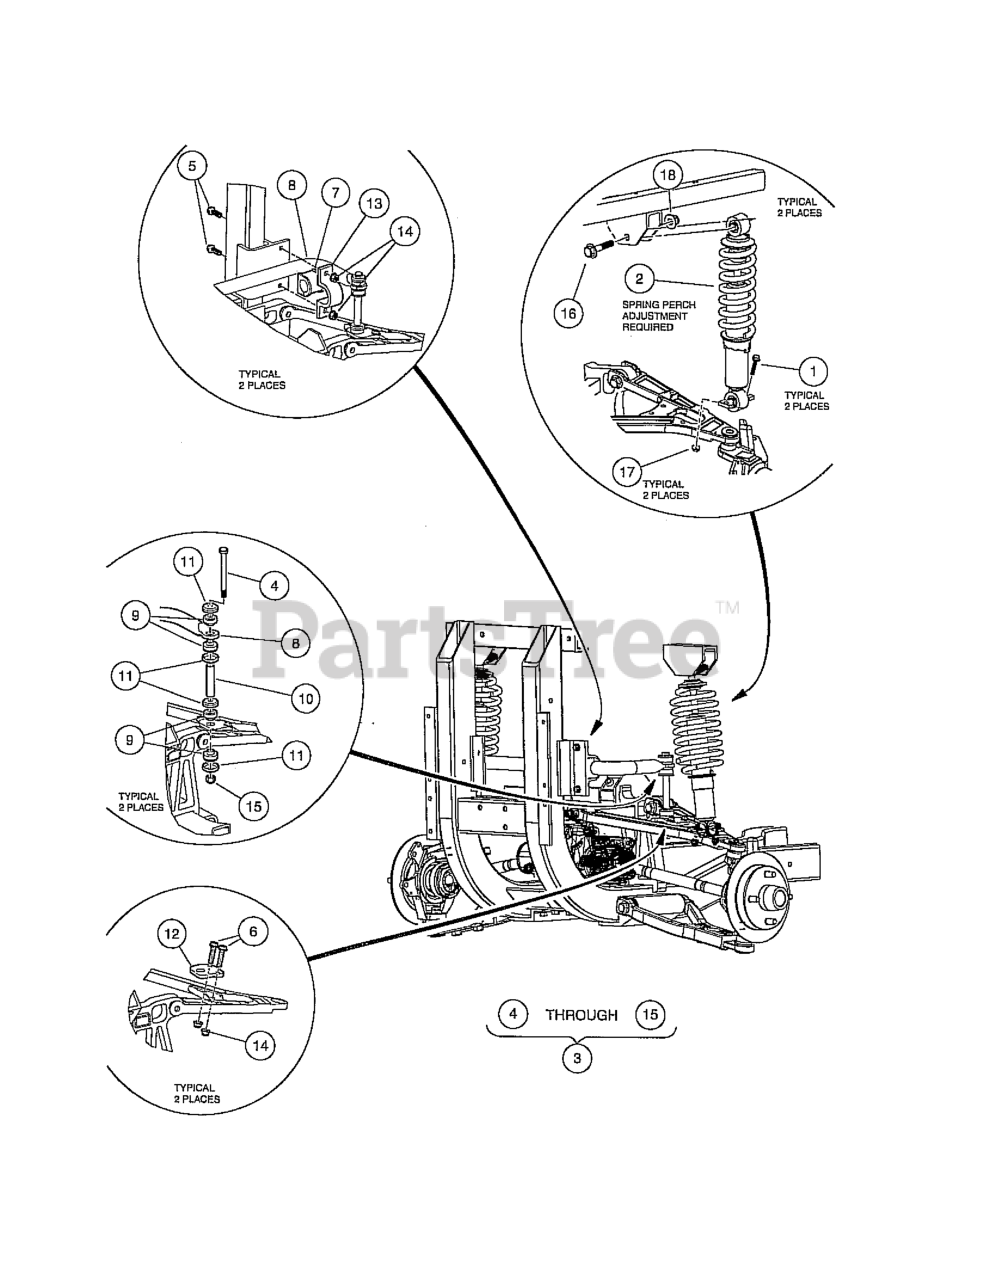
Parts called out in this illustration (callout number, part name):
1	BOLT, FLANGE HD, M8 X 40.0
2	SHOCK, COIL OVER, FRONT
3	KIT, ANTI-SWAY BAR
4	SCREW, 3/8-16 X 7.00 HEX CAP
5	BOLT - FLANGED HD, M8 X 30.0
6	BOLT, FLANGE HD, M8 X 40.0
7	BUSHING, ANTI-SWAY BAR, 1-1/8
8	BAR, SWAY, FORMED
9	BUSHING, LINK
10	SLEEVE, LINK
11	WASHER, CUP, BUSHING
12	MOUNT, LINK
13	BRACKET, ANTI-SWAY BAR
14	LOCK NUT, FLG M8 X 1.25 NYLON
15	LOCKNUT, 3/8-16 HEX
16	BOLT, FLG, M12X1.75X70
17	LOCK NUT, FLG M8 X 1.25 NYLON
18	NUT FLG, M12X1.75, NYLON GR 10
